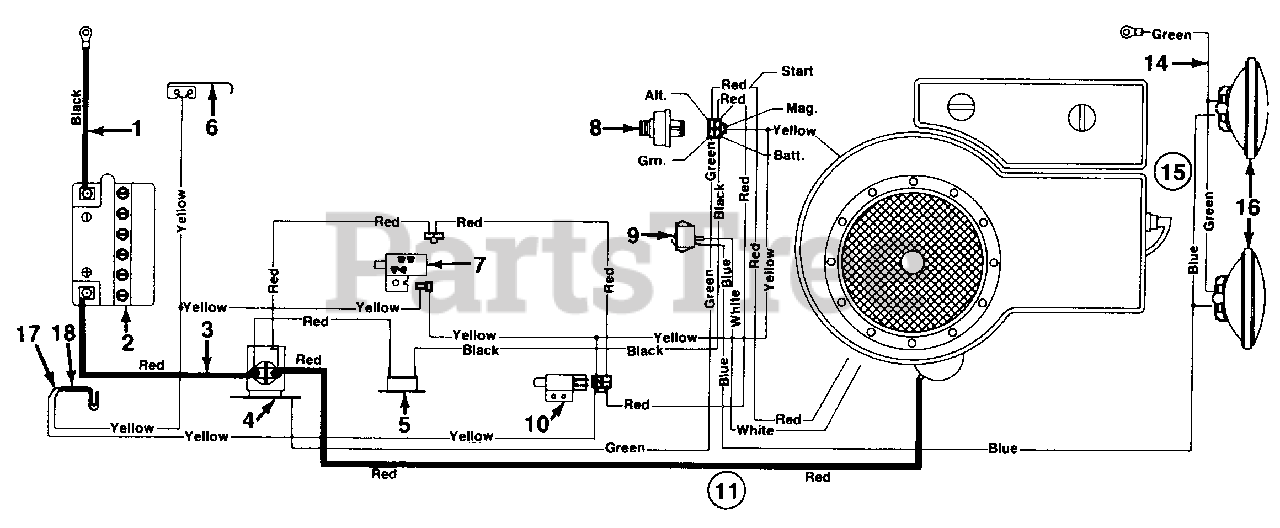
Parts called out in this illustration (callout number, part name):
2	Battery
3	Electric Wire-8.0" Lg.
4	Solenoid
5	Circuit Breaker
6	Spring Switch
7	Safety Switch
8	Ignition Switch
9	Light Switch
10	Safety Switch
15	Headlight Harness
16	Headlight
17	Safety Switch
18	Safety Switch
